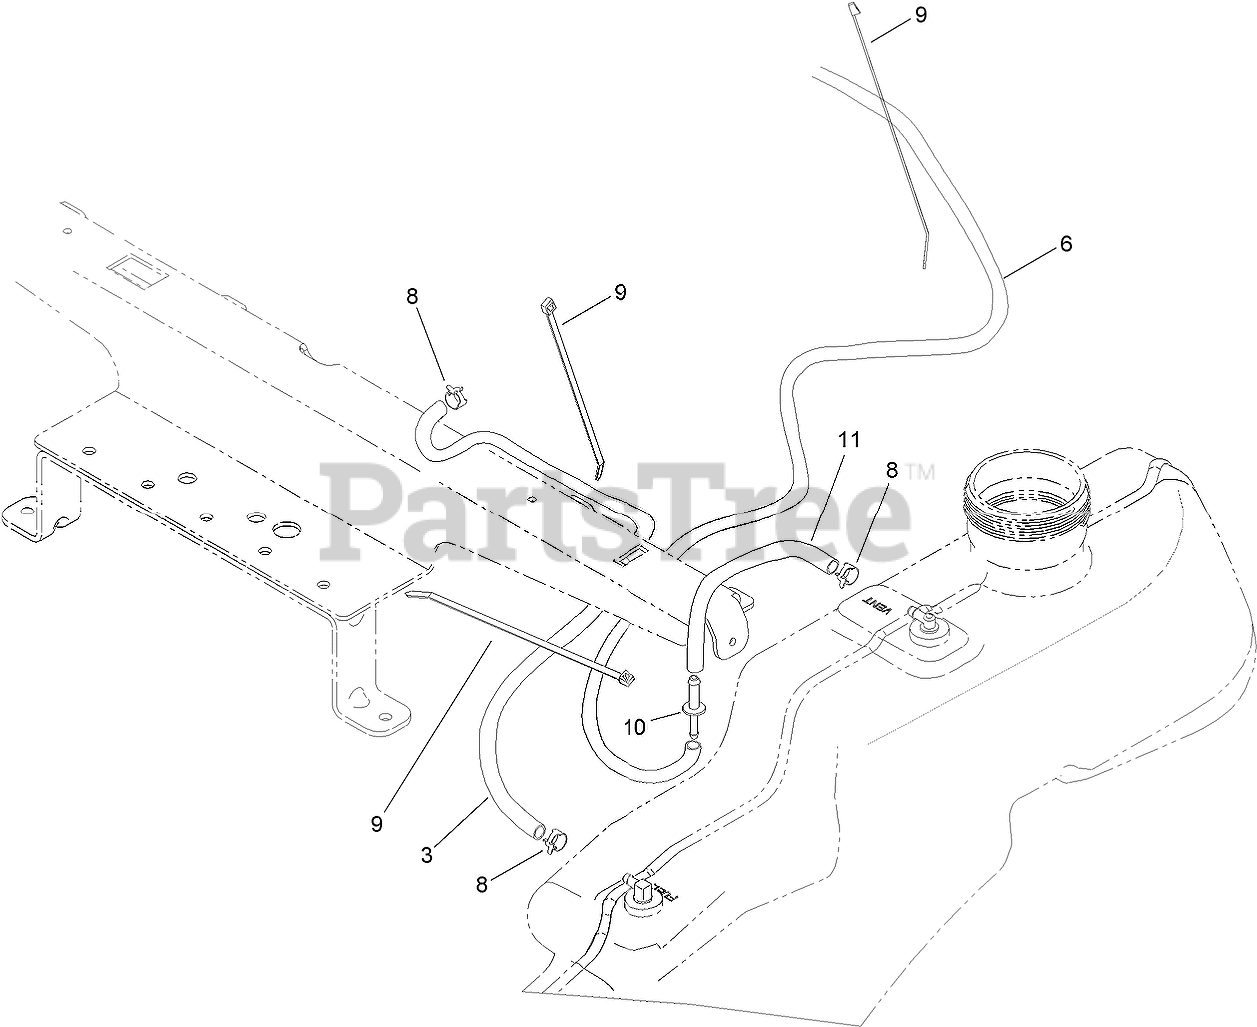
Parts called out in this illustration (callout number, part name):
3	HOSE-FUEL
6	HOSE-FUEL
8	CLAMP-HOSE
9	TIE-CABLE
10	ADAPTOR-ORIFICE
11	HOSE-FUEL
